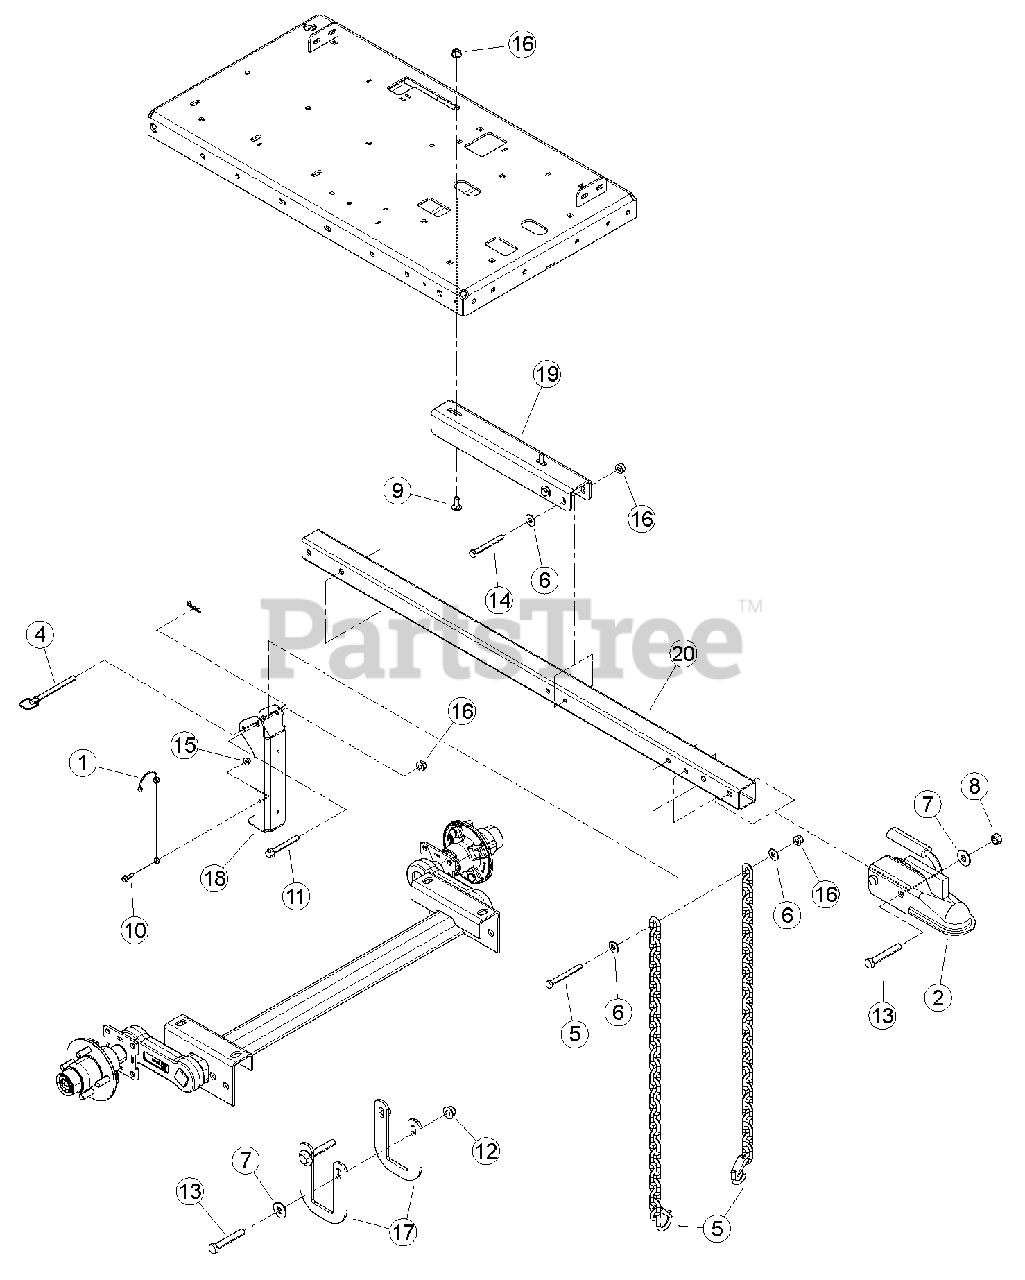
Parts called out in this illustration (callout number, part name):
1	LANYARD, NYLON
2	COUPLER, 50 MM BALL
3	CHAIN, SAFETY 5000 LB W/ LATCH
4	PIN, 3/8 HITCH
5	BOLT, 3/8 X 3-1/2" HEXHD GR5 ZP
6	WASHER, 3/8" FLAT ZP
7	WASHER, 1/2" FLAT Z
8	NUT, 1/2" CENTERLOCK GRB ZP
9	BOLT, 3/8 X 1" CRG GR5 NC ZP
10	BOLT, 1/4-20 X 3/4 HWH GR5 CZP
11	BOLT, 3/8 X 3 FLANGE NC
12	NUT, 1/2-13 NYLOCK FLANGE
13	BOLT, 1/2 X 3-1/4 HCS GR5 ZP
14	BOLT, 3/8 X 3-1/4 HEX HD GR5 ZP
15	NUT, 1/4-20 NYLOCK FLANGE
16	NUT, 3/8-16 NYLOCK FLANGE
17	PLATE, HITCH SADDLE
18	STAND, JACK
19	CHANNEL, HITCH POLE
20	TUBE, HITCH
